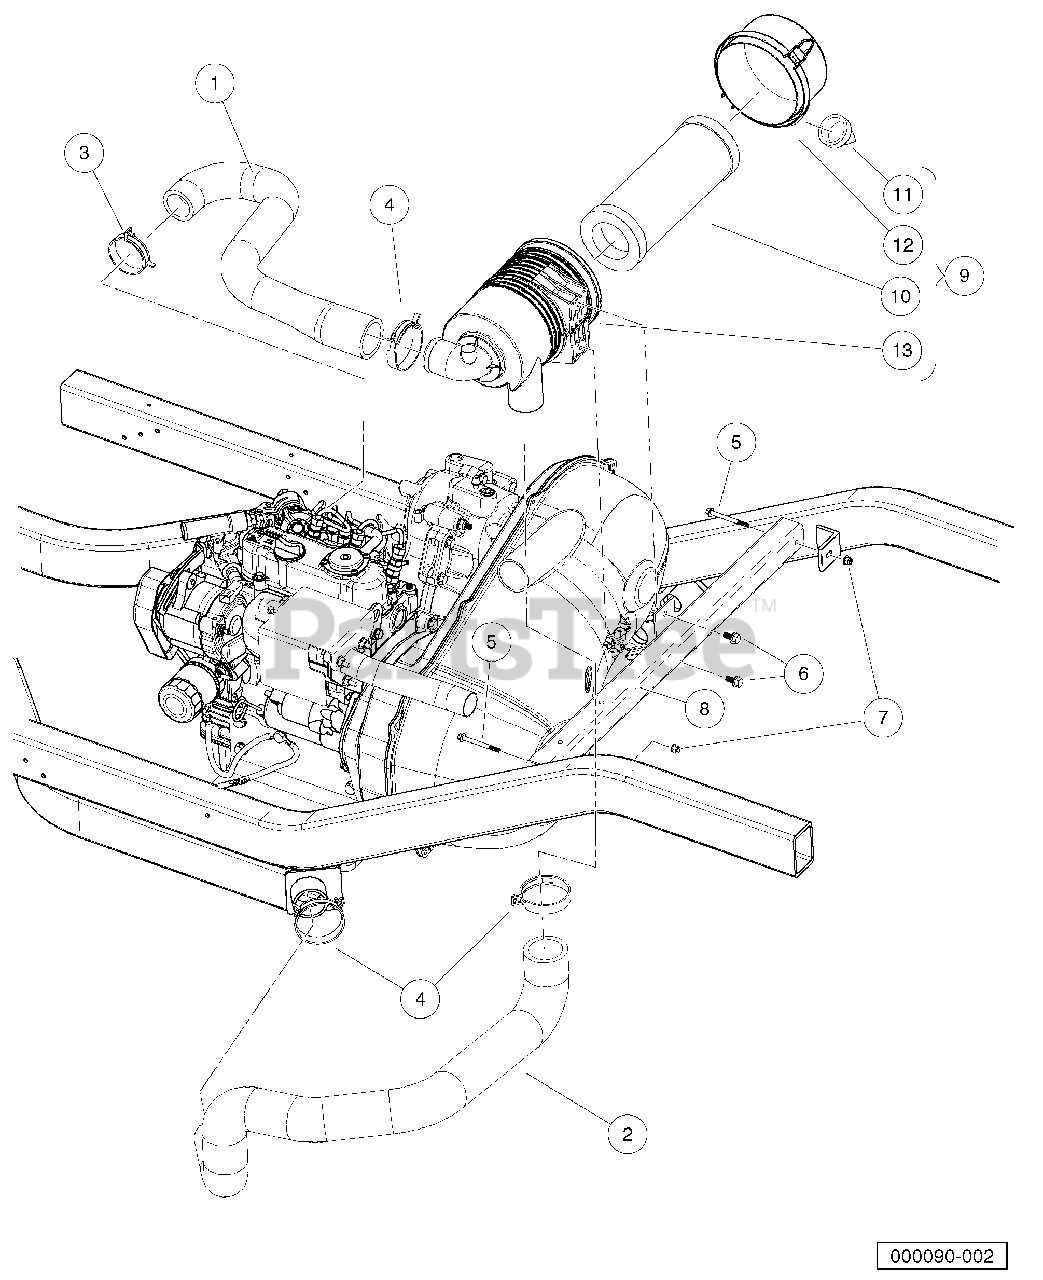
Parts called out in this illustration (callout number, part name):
1	Hose, Intake, D722
2	Hose, Intake, Primary
3	Clamp, Hose, Ctb 55mm
4	Clamp, Hose, Ctb 64mm
5	Bolt, M 6 X 1.0 X 65 Hex, Flange, Head, Black
6	Bolt Flanged Head, M8 X1.25x 16 with Loctite
7	Nut Flg, M6 X 1.0 Nylon
8	Weldment, Support, Air Cleaner
9	Filter, Air, Canister, W/labe
10	Element, Filter, Air, 5 In
11	Valve, Evacuator, Filter Air
12	Cap, Latch Lock, Filter, Air
13	Body, Canister, Filter, Air
